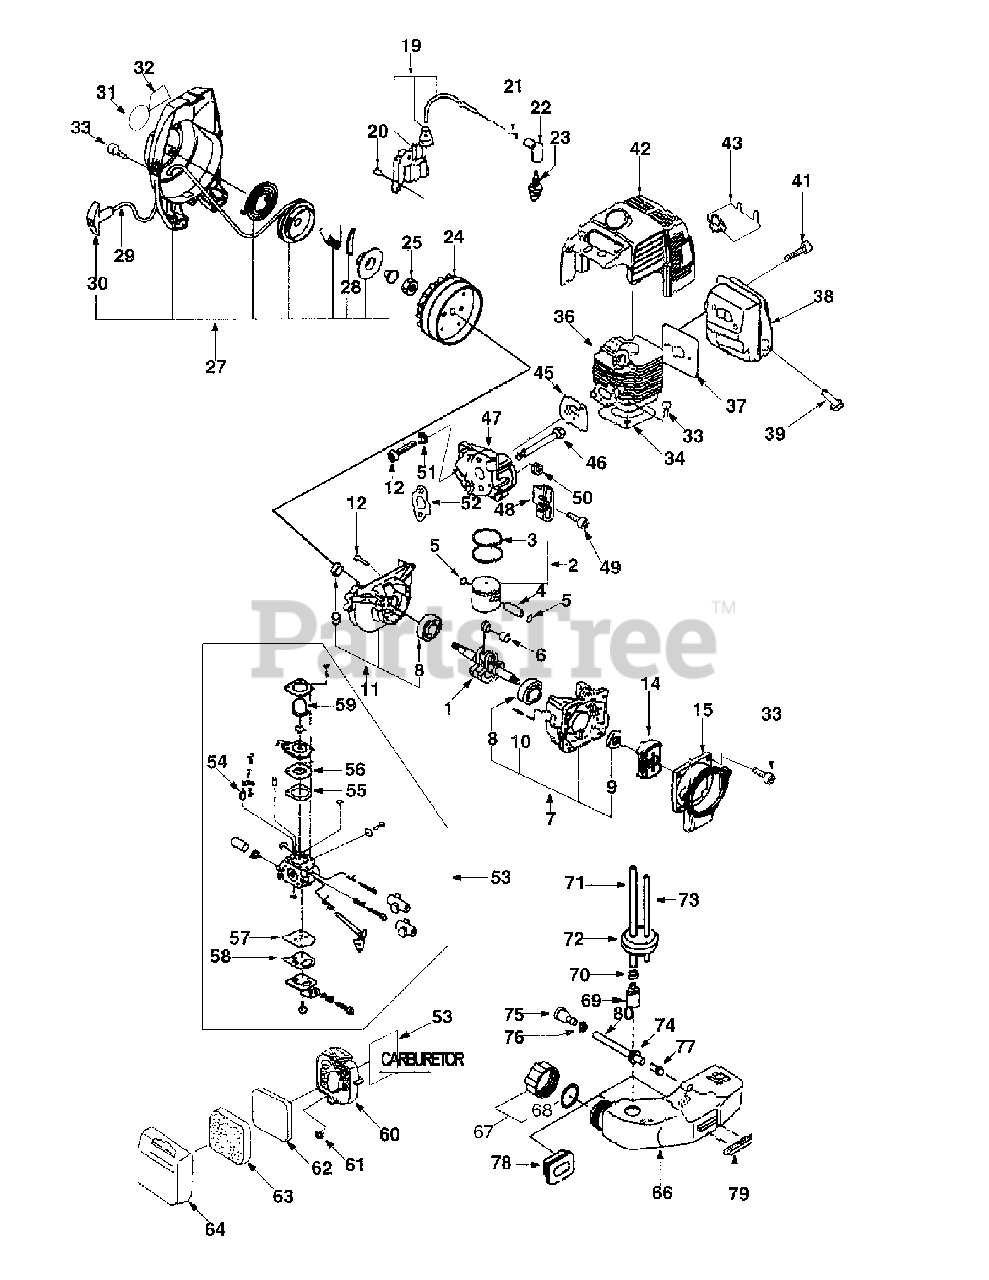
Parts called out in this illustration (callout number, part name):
1	Crankshaft
2	Piston Assembly
3	Ring, Piston
4	Pin, Piston
5	Clip, Piston Pin
6	Needle Bearing
7	Crankcase Assembly
8	Ball Bearing
9	Oil Seal
10	Dowel Pin
11	Crankcase Assembly
12	Bolt; M5 x 25
14	Clutch Assembly
19	Coil Assembly, Ignition
20	Bolt; M4 x 20
22	Cap, Plug
23	Spark, Plug
24	Flywheel, Magneto
27	Housing Assembly, Blower
29	Rope, Starter
30	Knob, Starter
31	Name Plate
32	Caution Plate
33	Bolt; M5 x 16
36	Cylinder
37	Gasket, Muffler
39	Arrester
41	Bolt; M5 x 48
42	Cowling, Cylinder
43	Baffle Plate
45	Gasket, Insulator
46	Bolt; M5 x 56
47	Insulator
48	Adjuster
49	Bolt; M5 x 12
51	Washer
52	Gasket, Carburetor
53	Carburetor Assembly
54	Valve, Float
56	Diaphragm, Metering
57	Diaphragm, Pump
60	Case, Air Silencer
62	Element (B), Air Filter
63	Element (A), Air Filter
64	Case, Cap
65	Wire Compl, Throttle
66	Tank, Fuel
67	Cap Assembly, Fuel Tank
69	Filter, Fuel
71	Hose
73	Hose
75	Valve Assembly, Reversing
77	Connector
79	Rubber
81	Gasket Kit
83	Spring, Spiral
